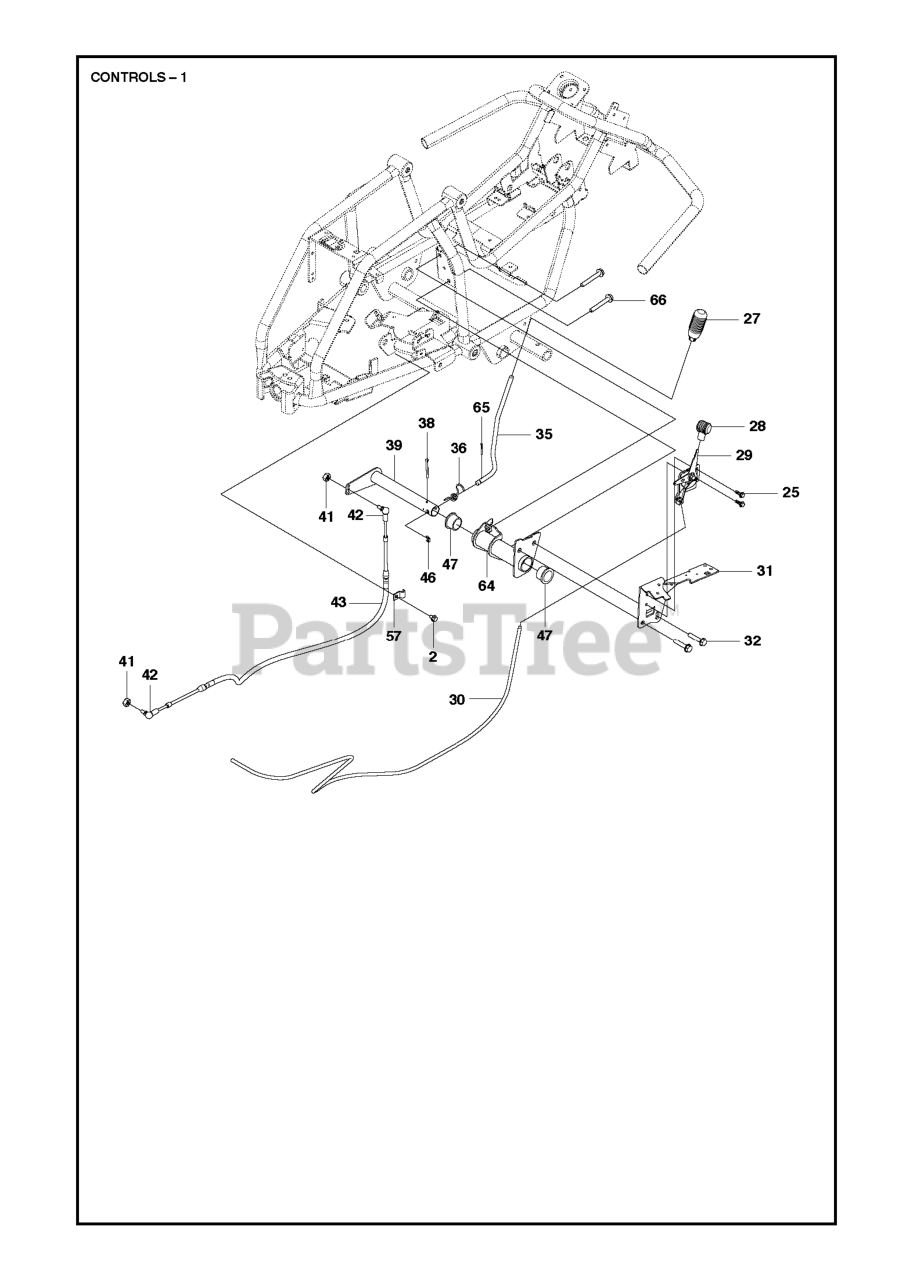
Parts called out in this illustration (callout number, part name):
27	GEAR STICK KNOB
29	THROTTLE CONTROL
41	LOCKNUT M5
42	CONNECTOR
46	Retaining Ring
47	BEARING FLANGE
65	Cotter Pin
66	SCREW
